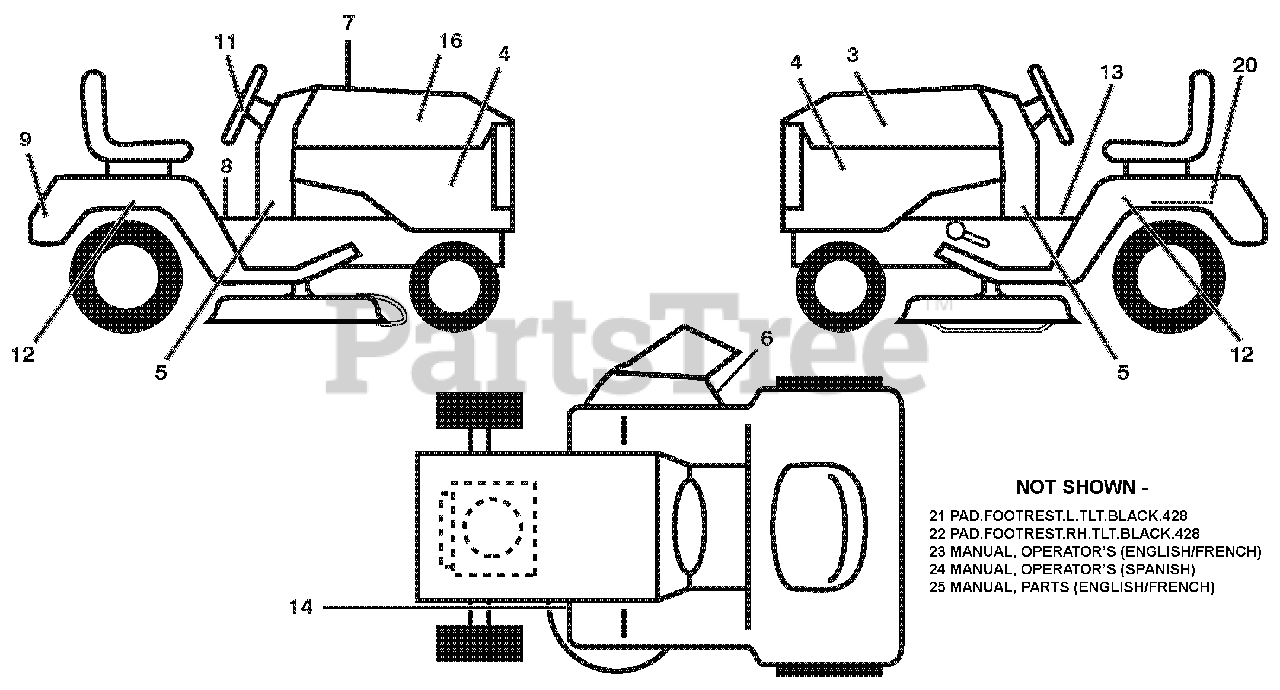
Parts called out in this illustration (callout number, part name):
3	DECAL.HOOD.LH.3HIGH.ARIENS
4	DECAL.SDPNL.PWRDBY KOHL.ARIENS
5	DECAL.DASH.LWR.18HP.ARIENS
6	DECAL.MOWER.WARN.KEEP HAND AWY
7	DECAL.RPL.KH(SNGL).TLW.42.PMST
8	DECAL.FENDER.WARNING.ENG/FR.07
9	DECAL.FENDER.REAR.ARIENS
11	DECAL.WHEEL.STEER.ARIENS
12	DECAL.FENDER.SIDE.GR.DR.ARIENS
13	Decal, Flag
14	DECAL.V-BELT.SCH.42/46"MEC/ELE
16	DECAL.HOOD.RH.3HIGH.ARIENS
20	DECAL.BAT.DAN/POI P/L SYM.WPN
21	PAD.FOOTREST.LH.TLT.BLACK.428
22	PAD.FOOTREST.RH.TLT.BLACK.428
23	MANUAL, OPERATOR'S (ENG/FRA)
24	MANUAL, OPERATOR'S (SPANISH)
25	MANUAL, PARTS (ENGLISH/FRENCH)
